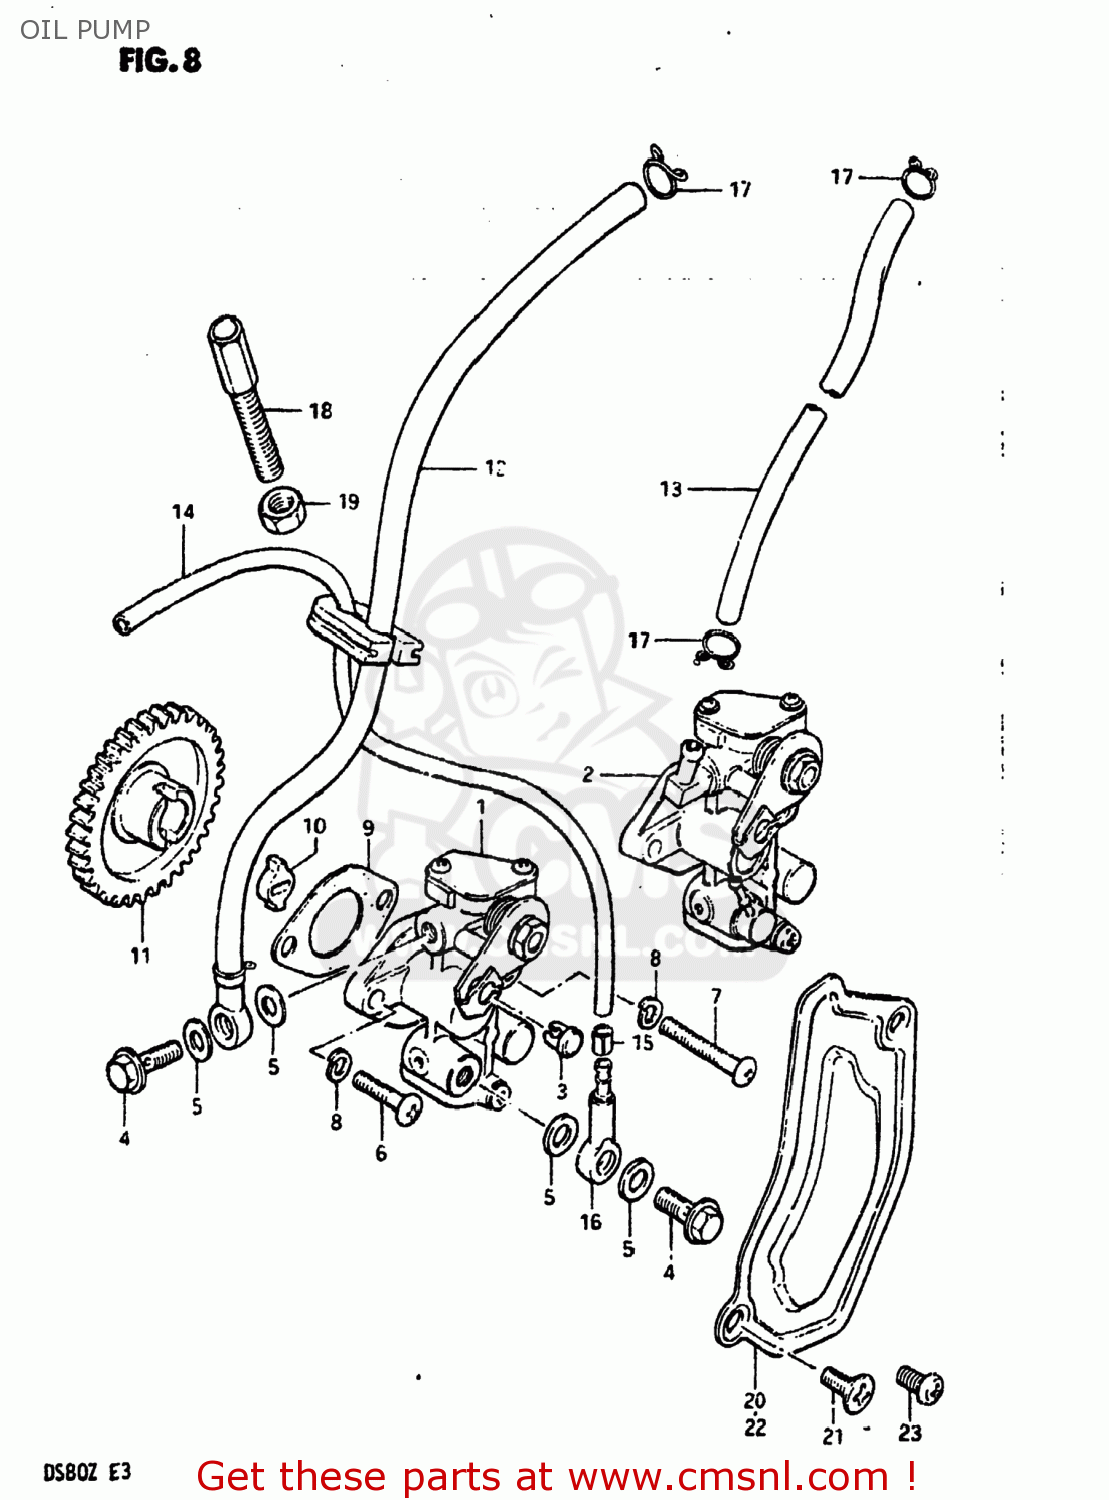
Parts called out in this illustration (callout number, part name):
1	PUMP ASSEMBLY,OIL
2	PUMP ASSY,OIL
3	TERMINAL,CABLE
4	UNION BOLT
5	GASKET(6.2X11X1).2 (NAS)
6	SCREW
7	SCREW
8	LOCK WASHER
9	GASKET,OIL PUMP (NAS)
10	PIECE,OIL PUMP DRIVE
11	GEAR,OIL PUMP DRIVE
12	HOSE,OIL NO.1
13	HOSE
14	HOSE,OIL
15	CLIP
16	VALVE,CHECK
17	CLIP
18	BOLT
19	NUT
20	CAP,OIL PUMP INSPECTION
21	SCREW
22	CAP,OIL PUMP INSPECTION
23	SCREW
